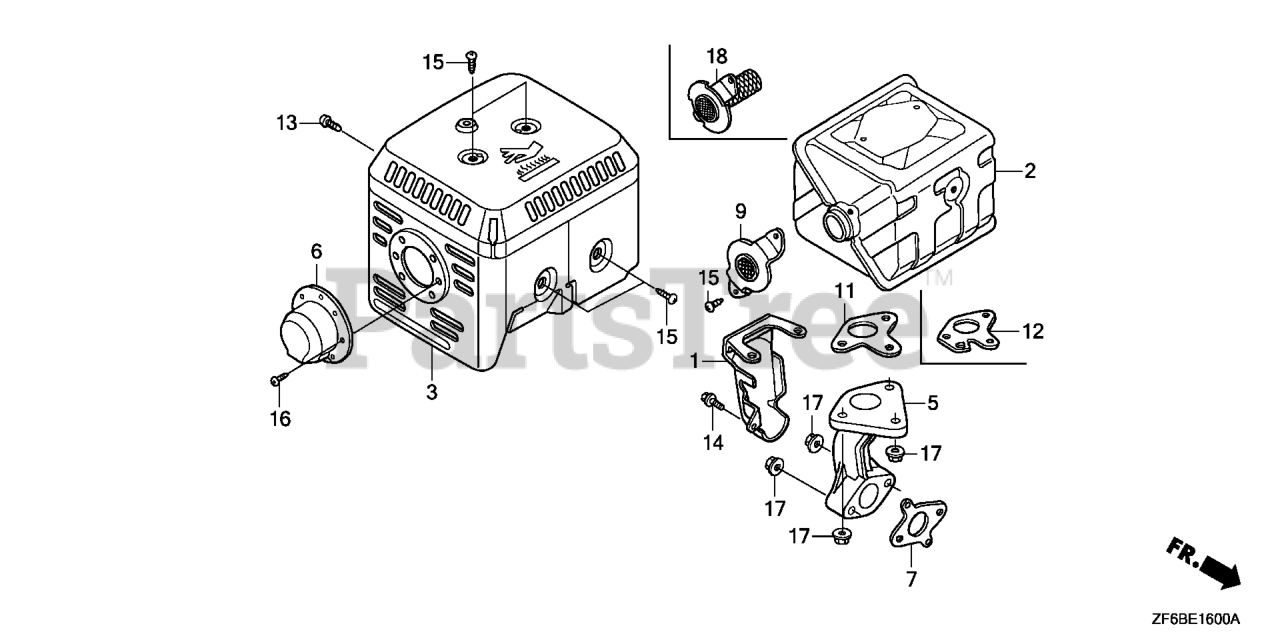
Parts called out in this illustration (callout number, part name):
1	PROTECTOR, EX. PIPE
2	MUFFLER
3	PROTECTOR, MUFFLER
7	GASKET, EX. PIPE
9	FLANGE, BAFFLE
11	GASKET, MUFFLER (NIPPON LEAKLESS)
12	GASKET, MUFFLER (ARRESTER)
13	SCREW, TAPPING (6X10)
14	BOLT, FLANGE (6X12) (CT200)
15	SCREW, TAPPING (5X8)
17	NUT, FLANGE (8MM)
18	ARRESTER, SPARK
